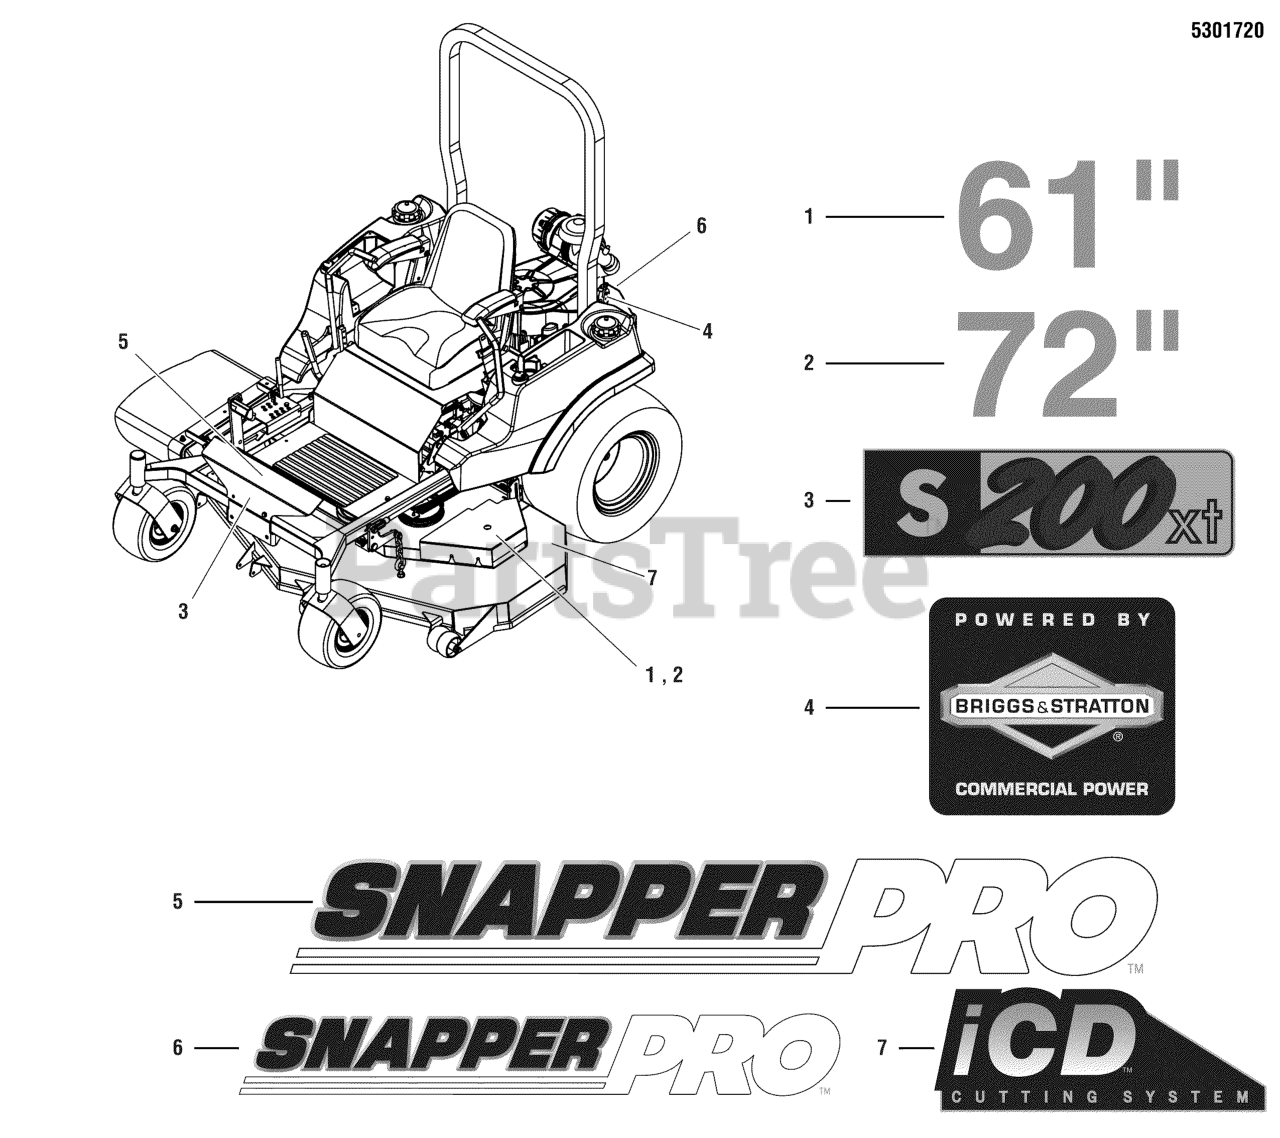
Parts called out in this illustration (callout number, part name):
1	DECAL, 61
2	DECAL, 72
3	DECAL, SNAPPER PRO, S200XT
5	DECAL, SNAPPER PRO, FRONT
6	DECAL, SNAPPER PRO, HEAT
7	DECAL, iCD CUTTING SYSTEM
